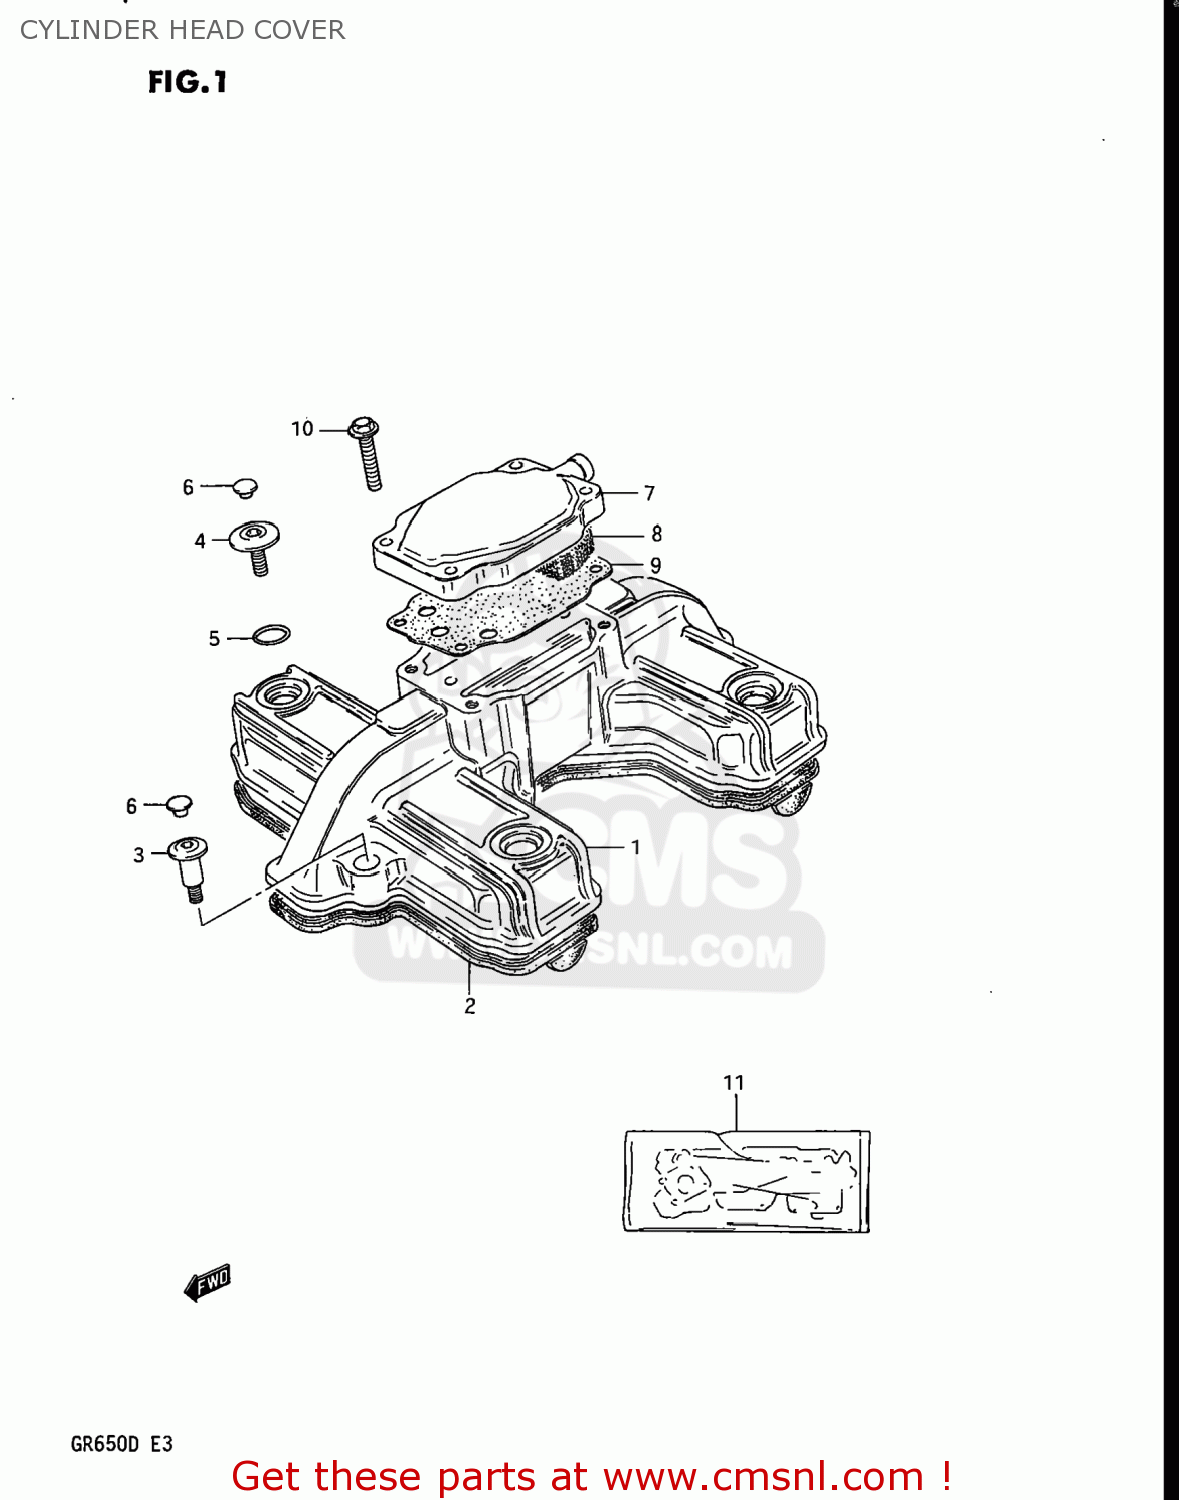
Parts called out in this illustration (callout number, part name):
1	COVER,CYLINDER HEAD
2	GASKET,CYLINDER HEAD COVER (NAS)
3	BOLT(7X19)
4	BOLT(7X5.5)
5	O RING(D:1.9,ID:14.5)
6	CAP(OD:10)
7	COVER,BREATHER
8	SEPARATOR,OIL BREATHER CO
9	GASKET (NAS)
10	BOLT
11	GASKET
